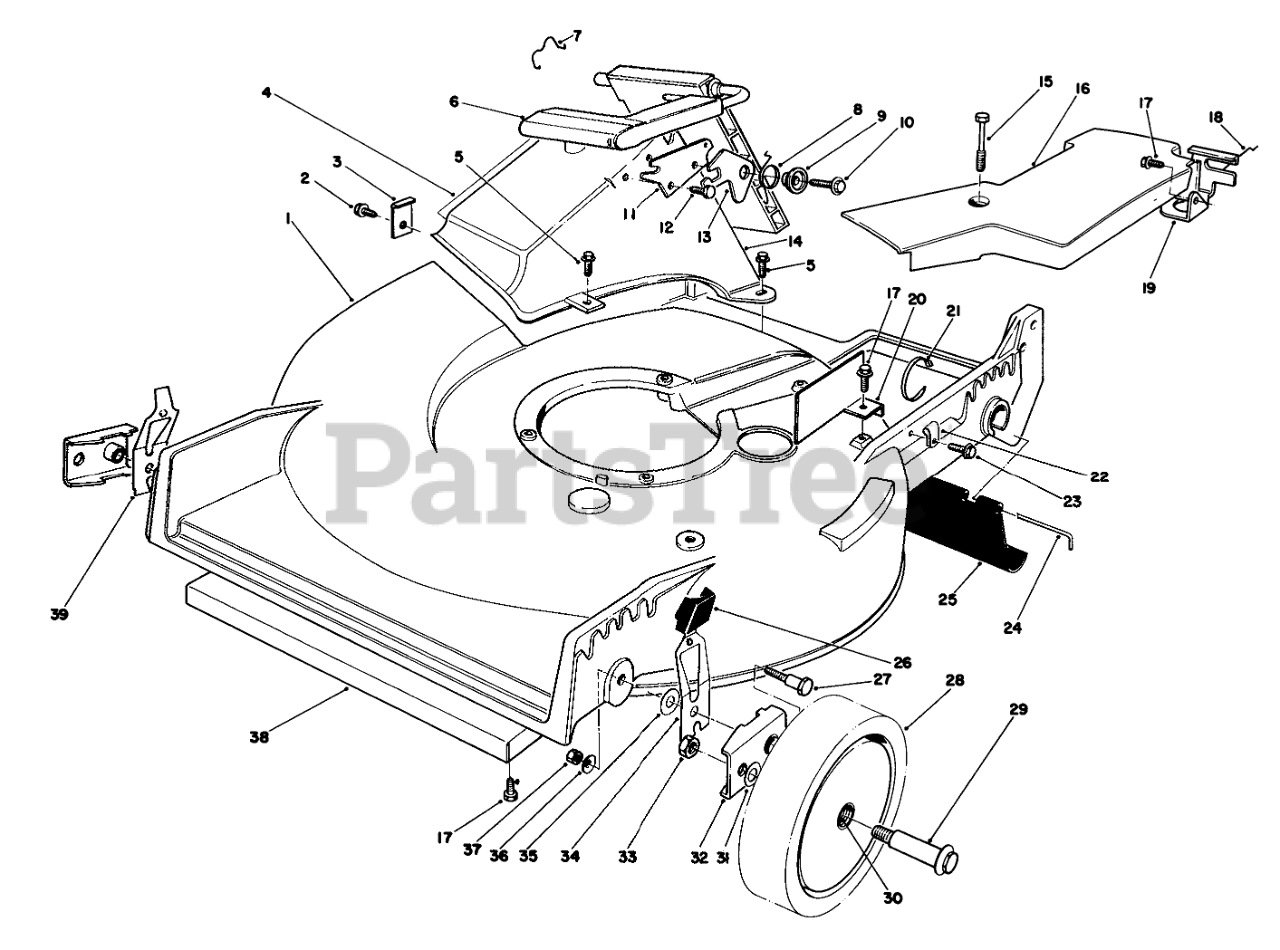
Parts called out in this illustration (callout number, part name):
1	21 SP RB HSG/DECAL
2	SCREW
3	TUNNEL CLIP
4	ATTENTION DECAL
5	SCREW-HWH
6	Discharge Door Assembly
7	DOOR RET SPRING
8	TORSION SPRING
9	DOOR SPACER
10	SCREW-HWH
11	DOOR LATCH PLATE
12	SCREW-PLASTITE
13	SAFETY LATCH
14	Tunnel Discharge
15	SCREW-HHFTF
16	Cover-Belt
17	SCREW-HWHTF
18	RETAINER-CABLE
19	Bracket-Traction Adj.
20	Shield-Muffler
21	TIE-CABLE
22	CLAMP-CABLE
23	SCREW
24	ROD-SHIELD
25	SHIELD-TRAILING
26	KNOB-ARM
27	PIVOT SCREW
28	Wheel & Tire Assembly (Incl. Ref. #30)
29	BOLT-WHEEL
30	BUSHING
31	WASHER
32	HP PIVOT ARM ASM
33	Nut
34	L. HP SPRING ARM ASM
35	WASHER-PIVOT
36	WASHER-BELLEVILLE
37	NUT-LOCK, NI
38	Shield-front
39	R HP SPRING ARM ASM
